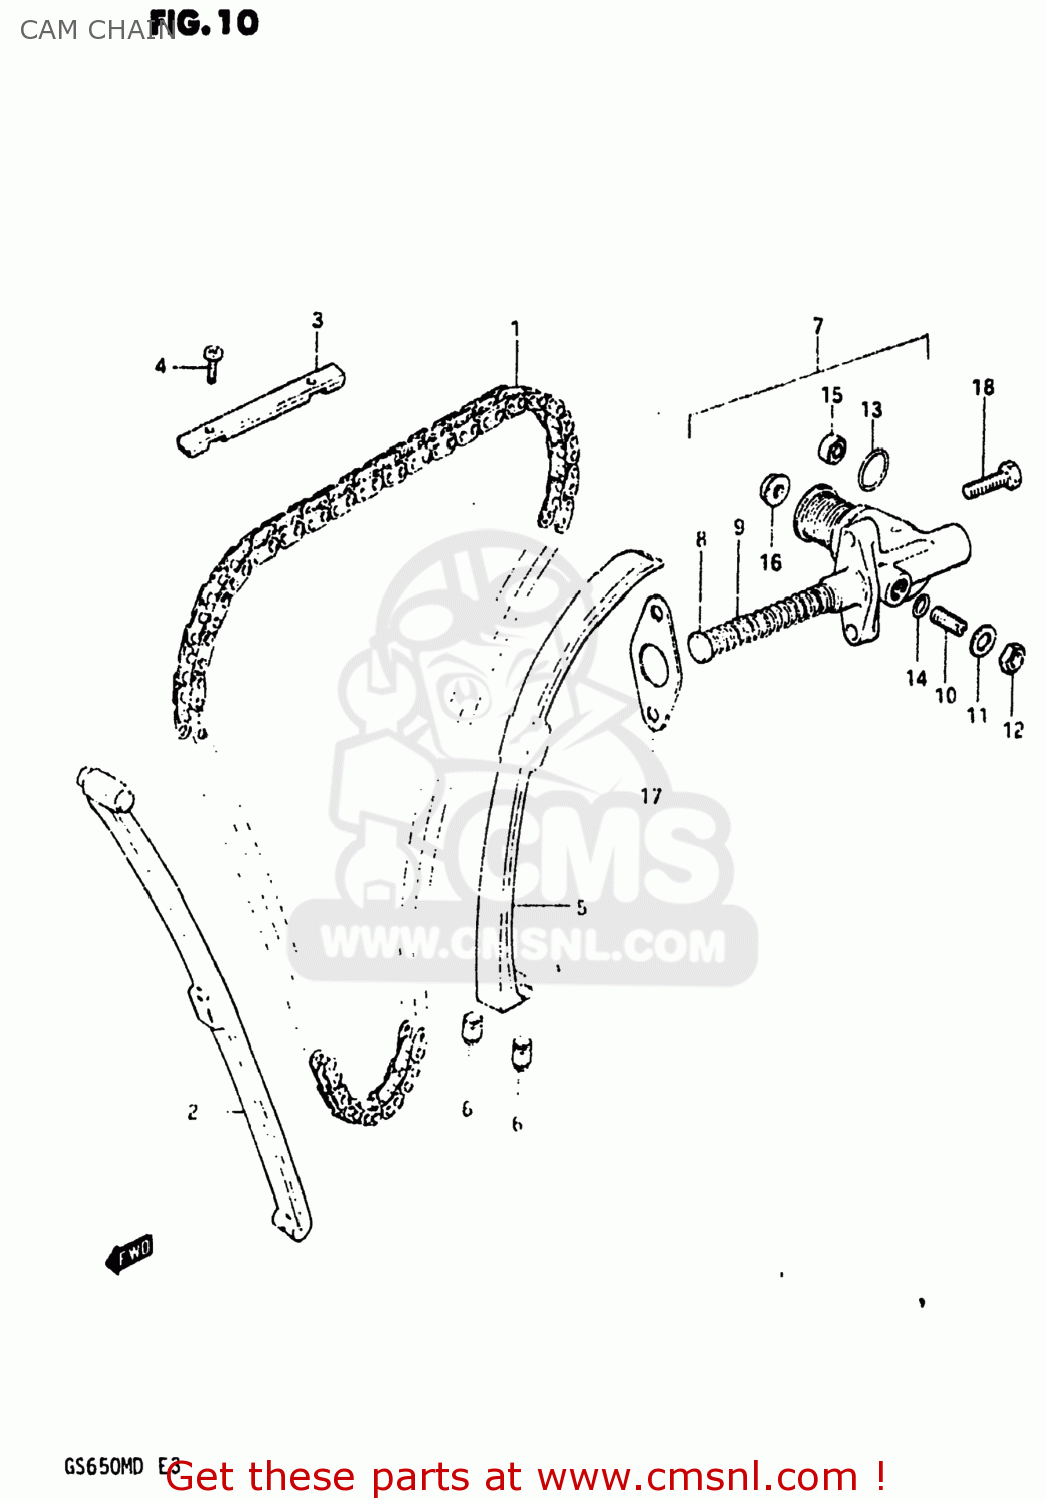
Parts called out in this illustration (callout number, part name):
1	CHAIN,CAMSHAFT DRIVE(120L)
2	GUIDE,CAM CHAIN
3	GUIDE,CAM CHAIN
4	SCREW
5	TENSIONER,CAM CHAIN
6	CUSHION,CAM CHAIN TENSIONER
7	ADJUSTER ASSEMBLY,TENSIONER
8	ROD,PUSH
9	SPRING
10	SCREW,TENSIONER ADJUST
11	WASHER,8.5X16X
12	NUT
13	O-RING
14	O-RING
15	OIL SEAL
16	NUT
17	GASKET,TENSIONER ADJUSTER (MCA)
18	SCREW
